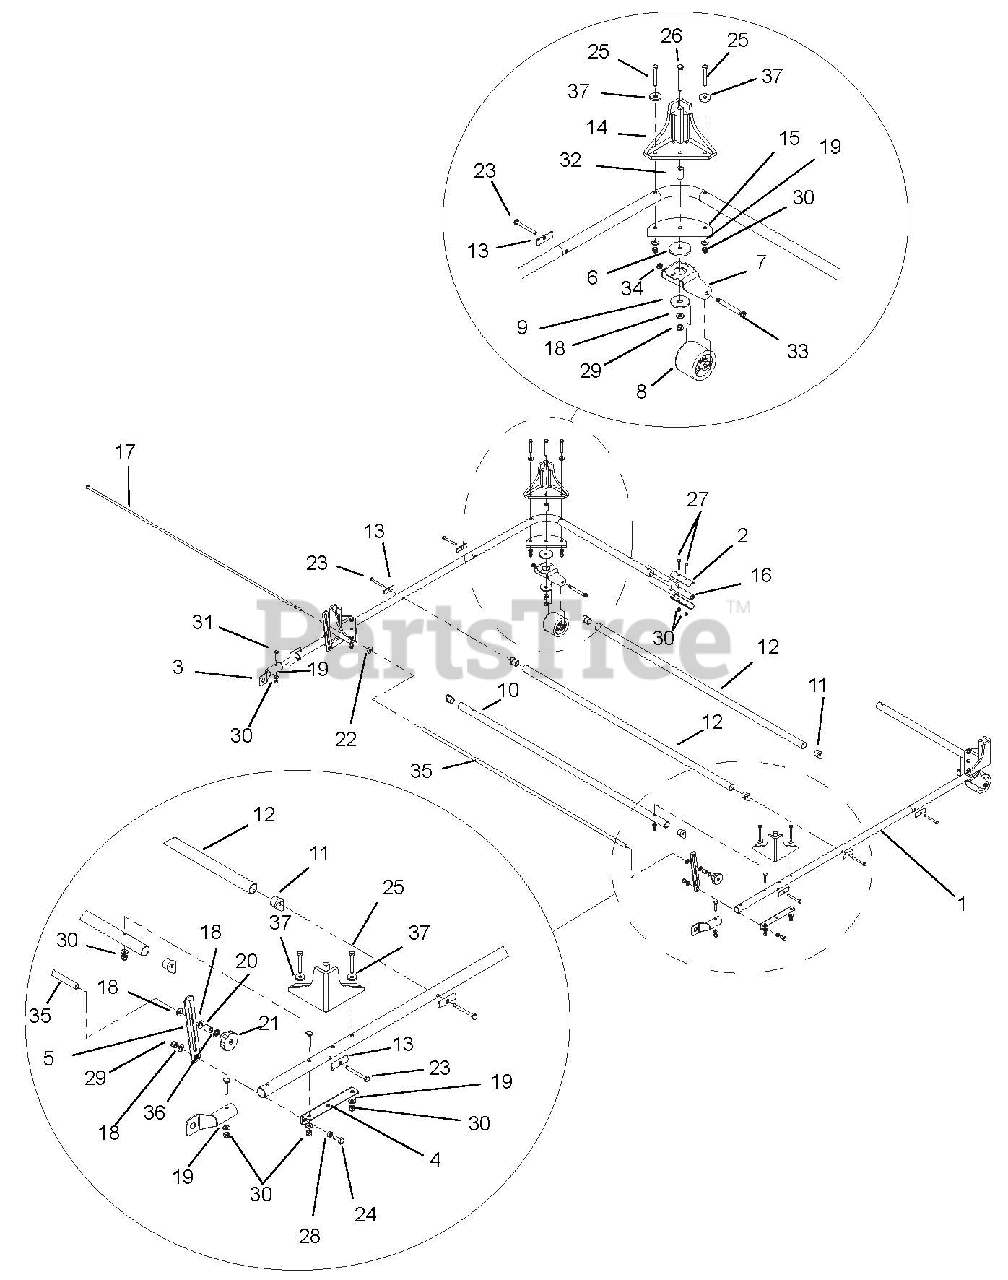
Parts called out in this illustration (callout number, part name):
1	Frame Side
2	Clamp, Half
3	End Cap, Tube
4	Angle Bracket
5	Bracket, Adjust
7	Caster Fork
9	Washer, Area Vac 35 29/64 x 1-3/4 x.134
10	Cross Brace, Forward
11	Tube Connector, Round To Round
12	Cross Brace Assembly, Middle
13	Clamp, Bracket
14	Support, Corner
15	Caster Plate
16	Insert, Tube
17	Bolt, Adjuster
18	Washer, Flat Steel .344 x .688 x .065 YWZC
19	Washer, Flat Steel .281 x .62 x .065 YWZC
20	Spacer, .500 OD x .625 L
21	Knob, Fluted
22	Washer, Flat Steel .438 x 1.00 x .083 YWZC
23	Bolt, Hex .25-20 x 2.50 Grade 5 YWZC
24	Bolt, Hex .31-18 x .75 Grade 5 YWZC
25	Bolt, Hex .25-20 x 2.00 Grade 5 YWZC
26	Bolt, Hex .31-18 x 2.50 Grade 5 YWZC
27	Bolt, Hex .25-20 1.50 Grade 5 YWZC
29	Nut, Nylock .312-18 YWZC
30	Nut, Nylock .250-20 YWZC
31	Bolt, Contour Head 1/4-20 x 1.50
33	Bolt, Shoulder Socket 3/8 x 2-3/4
34	Nut, Lock Center, .25-20 YWZC
35	Tube, Plated 1/2 x .065
36	Washer, Lock .38 Internal Star YWZC
37	Washer, Flat Steel .328 x .87 x .179 YWZC
